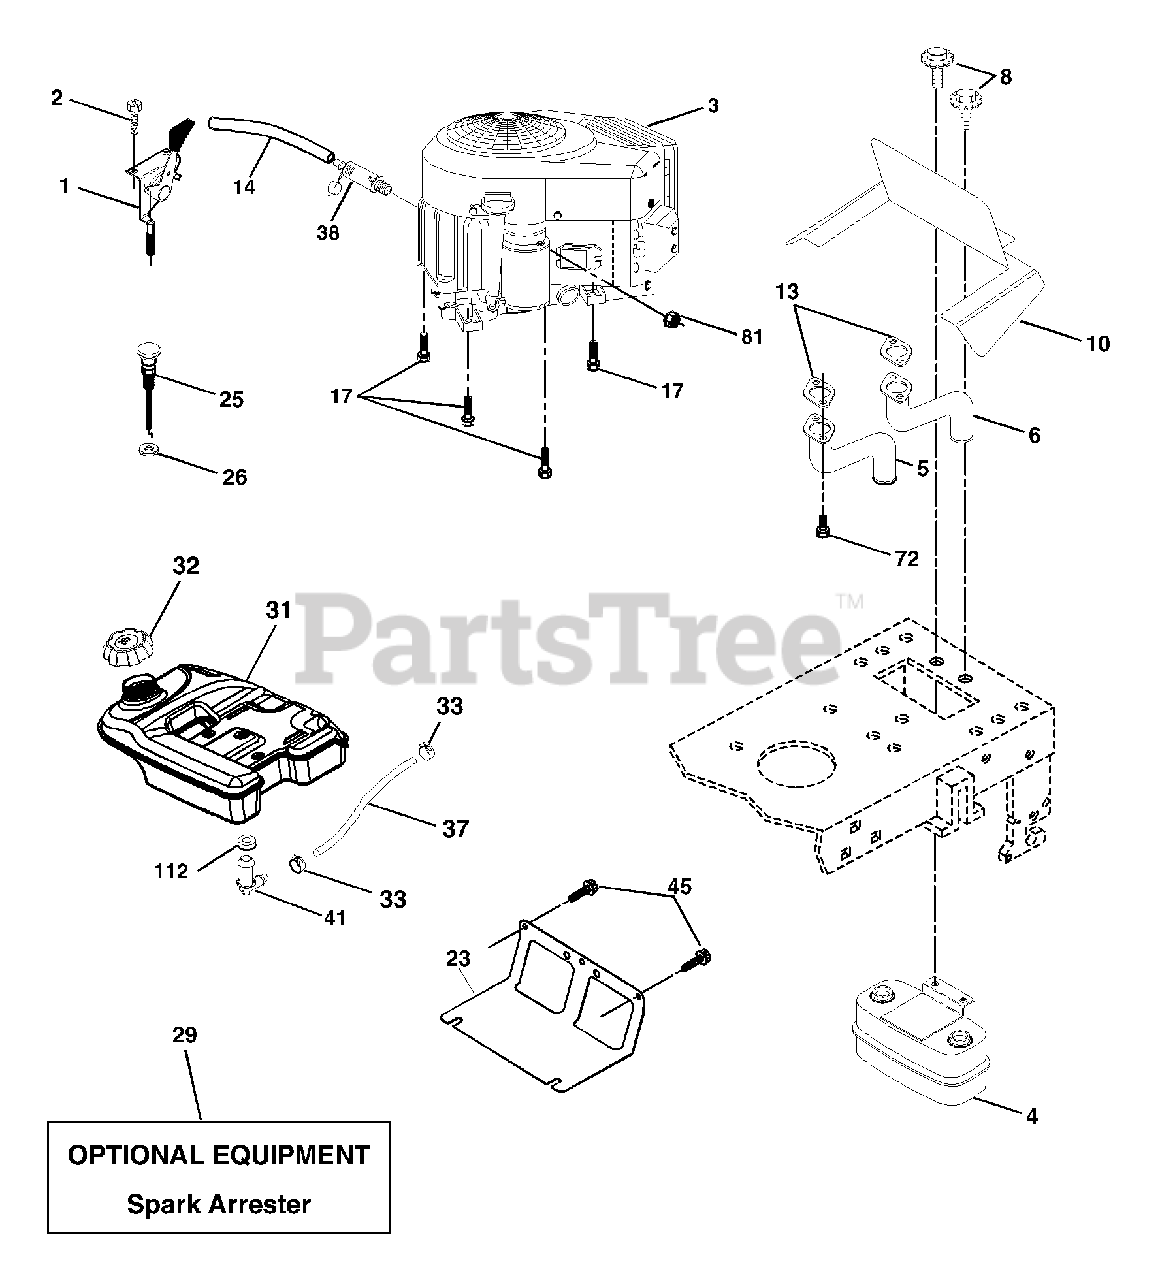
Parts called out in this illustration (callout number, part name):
1	Control Th/ch Flag
2	Screw Hex Thd Cut 1/4-20 x 1/2
5	Exhaust Tube LH
6	Exhaust Tube RH
8	Bolt 5/16-18 unc x 3/4
10	Shield Heat Muffler
14	Tube Drain Oil Easy
17	Screw 3/8-16 x 1-1/2
23	Shield Browning/Debris Guard
25	Control Choke
26	Nut Keps 3/8-24 unf
29	Kit Spark Arrestor (Flat Scrn)
32	Cap Asm Fuel
33	Clamp Hose Black
37	Line Fuel
38	Plug Drain Oil Easy
41	Stem Tank Fuel
45	Screw Hex Wsh Thdr 3/8-16 x 3/4
72	Screw Socket Head 5/16-18 x 1
81	Nut Keps Hex 1/4-20 Starter Nut
112	Bushing
